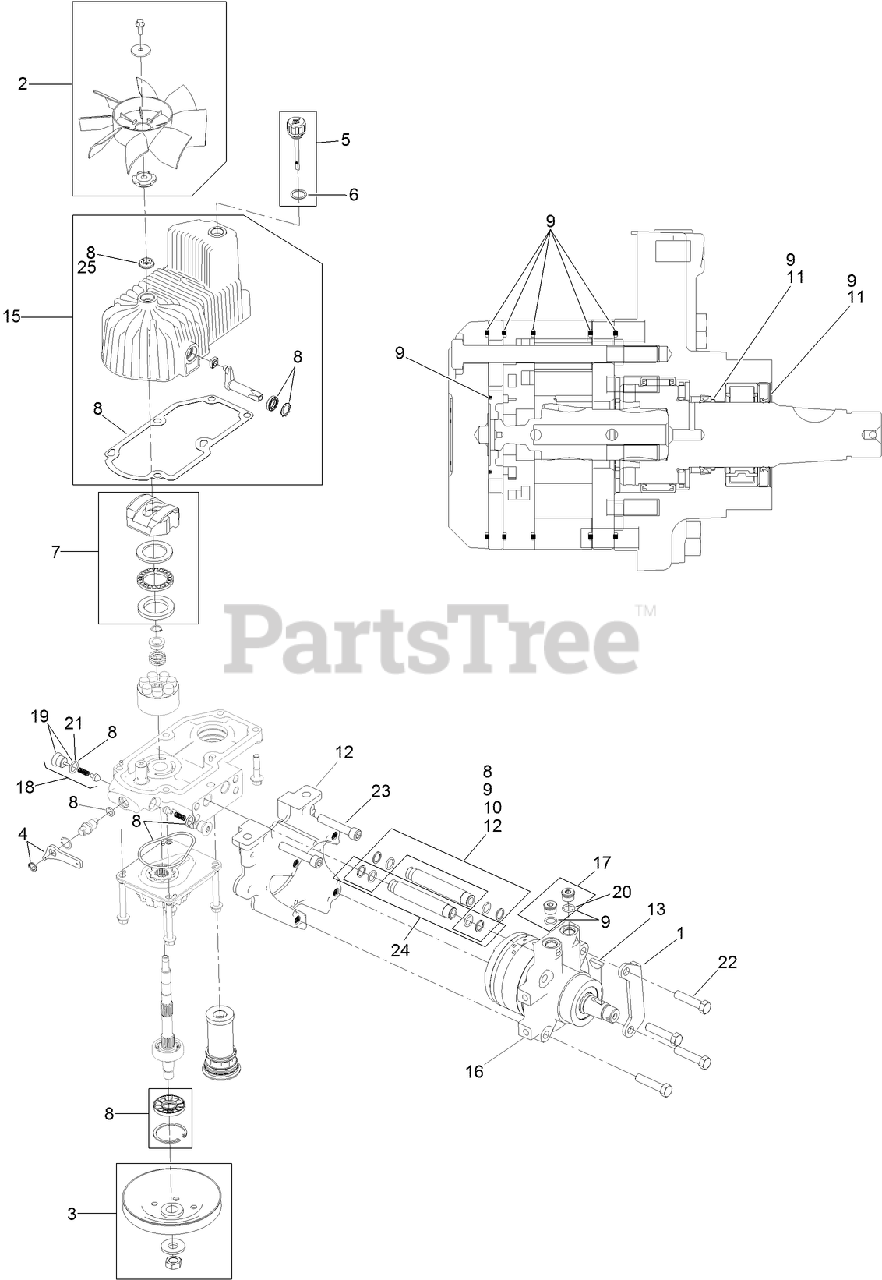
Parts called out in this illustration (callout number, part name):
1	MOUNT-SHOE, HORSE
2	FAN KIT
3	PULLEY KIT
4	HANDLE-BYPASS VALVE, HYDRO
5	DIPSTICK-HYDRO W/GASKET
6	GASKET-DIPSTICK, HYDRO
7	SWASH BLOCK KIT
8	PUMP SEAL KIT
9	MOTOR SEAL KIT
10	TUBE SEAL KIT
11	OUTPUT SHAFT SEAL KIT
12	NOSE CUP-UHT
13	KEY-WOODRUFF
15	HOUSING-HYDRO, RH
16	MOTOR-HYDRAULIC RH 240CC
17	MAGNETIC PLUGS SERVICE KIT
18	CHECK VALVE ASM
19	PLUG-CHECK (W/O-RING)
20	O-RING
21	O-RING-CHECK VALVE
22	SCREW HH
23	SCREW-HSH
24	HYDRAULIC TUBE KIT
25	SEAL-FAN DRIVE
